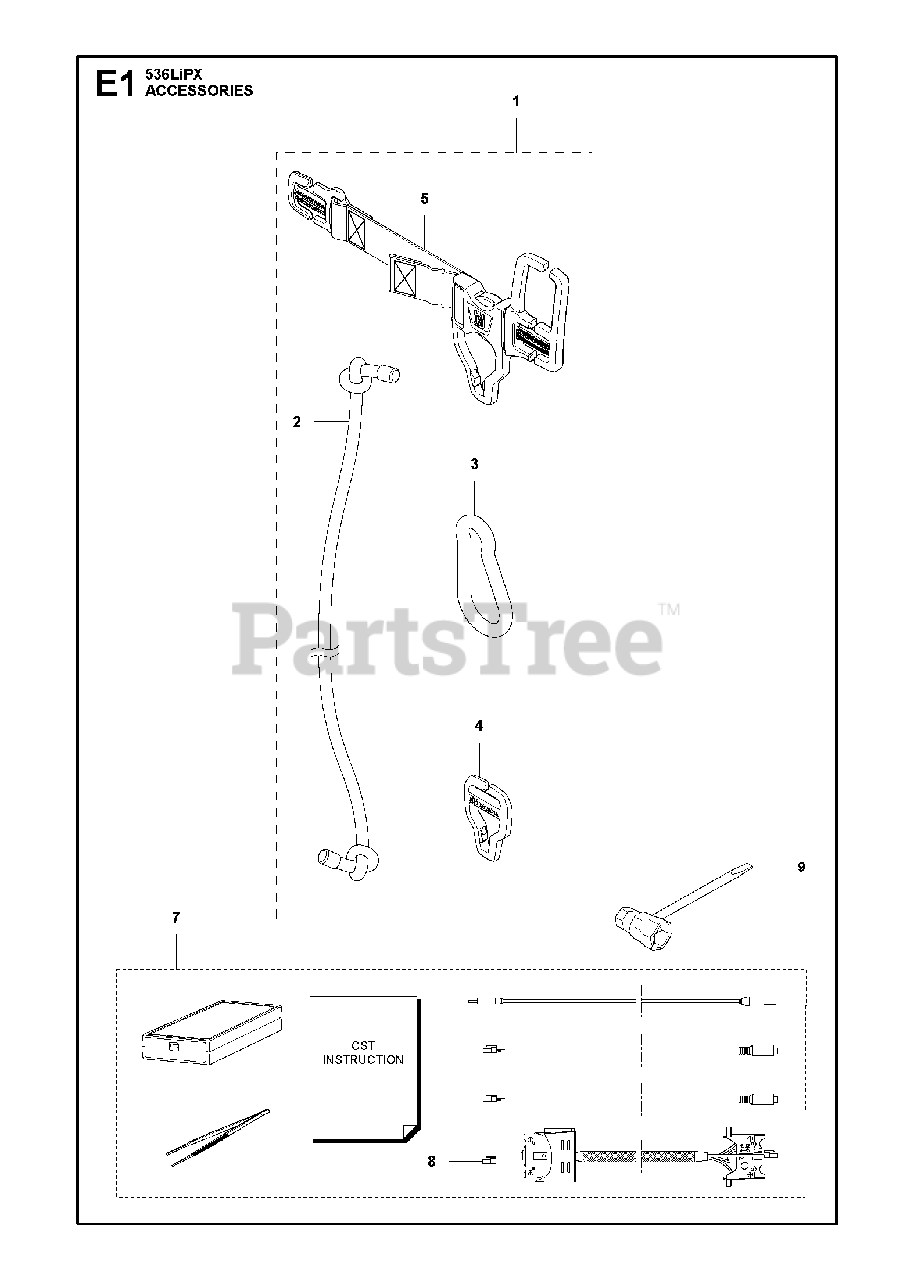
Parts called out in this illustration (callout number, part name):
7	DIAGNOSTIC TOOL KIT
8	WIRING ASSY
9	COMBI TOOL
